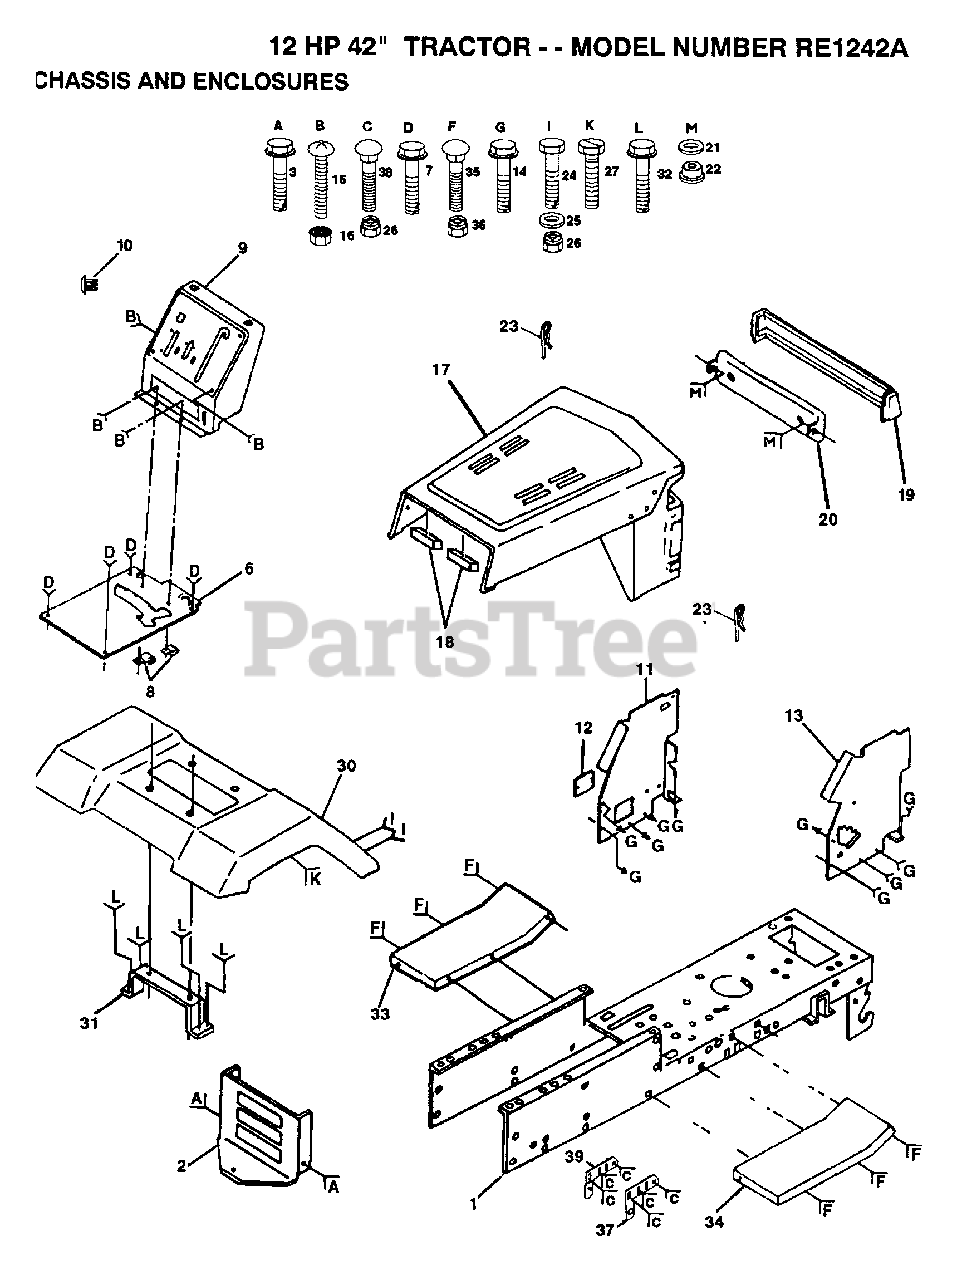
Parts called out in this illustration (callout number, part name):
3	SCREW
7	SCREW LT
8	CLIP T
10	PLUG BUTTON T
11	PANEL DASH LH
12	COVER ACCESS
14	SCREW LT
15	SCREW
17	HOOD/GRILL ASM
21	WASHER PM
22	PAL NUT LT
23	SPRING.RETAINER
25	WASHER
27	SCREW LT
32	SCREW
33	FOOTREST LH
34	FOOTREST
35	BOLT
37	PIVOT BRKT RH
38	BOLT
39	PIVOT BRKT LH
